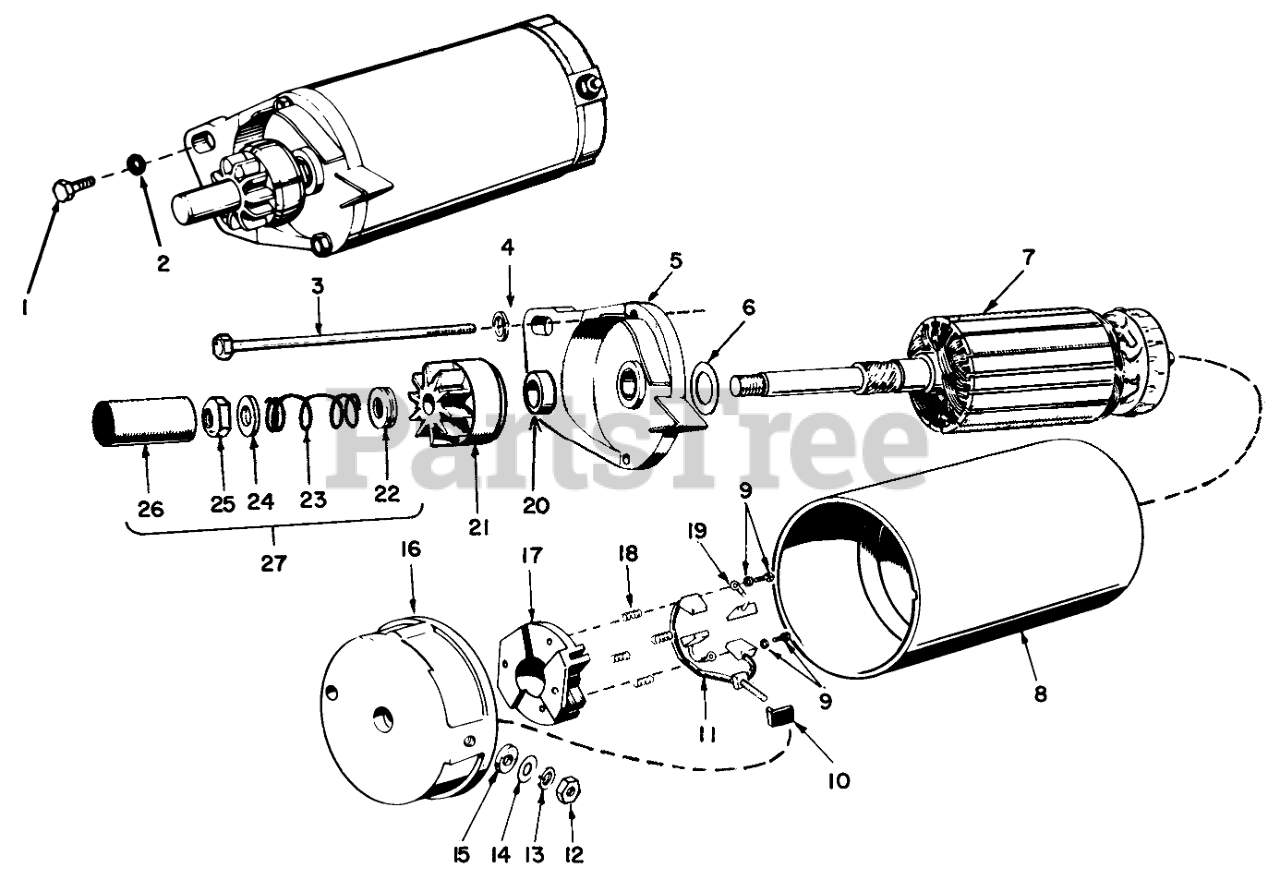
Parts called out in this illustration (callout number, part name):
1	Screw-Cap, Hex Hd.
2	Washer, Flat
3	Screw-Hex Hd.
4	Washer, Lock
5	Cap Assembly, Drive End
6	Washer, Armature Thrust
7	Armature
8	Housing, Starter Motor
9	Screw and Lockwasher
10	Bushing Insulation-Input Stud
11	Stud and Brush Assembly Input
12	Nut, Securing-Input Stud
13	Washer, Lock-Input Stud
14	Washer, Flat-Input Stud
15	Washer, Insulation-Input Stud
16	Cap Assembly, Commatator (Incl. Ref. #10-15 & 17-19 & 21)
17	Brush Holder
18	Spring, Brush
19	Brush, Ground
20	Cap, Dust
21	Drive Assembly
22	Spacer, Dust Cover
23	Spring, Anti-Drift
24	Washer, Stop Nut
25	Nut, Stop
26	Cover, Dust
27	Dust Cover Assembly (Incl. Ref. #22-26)
